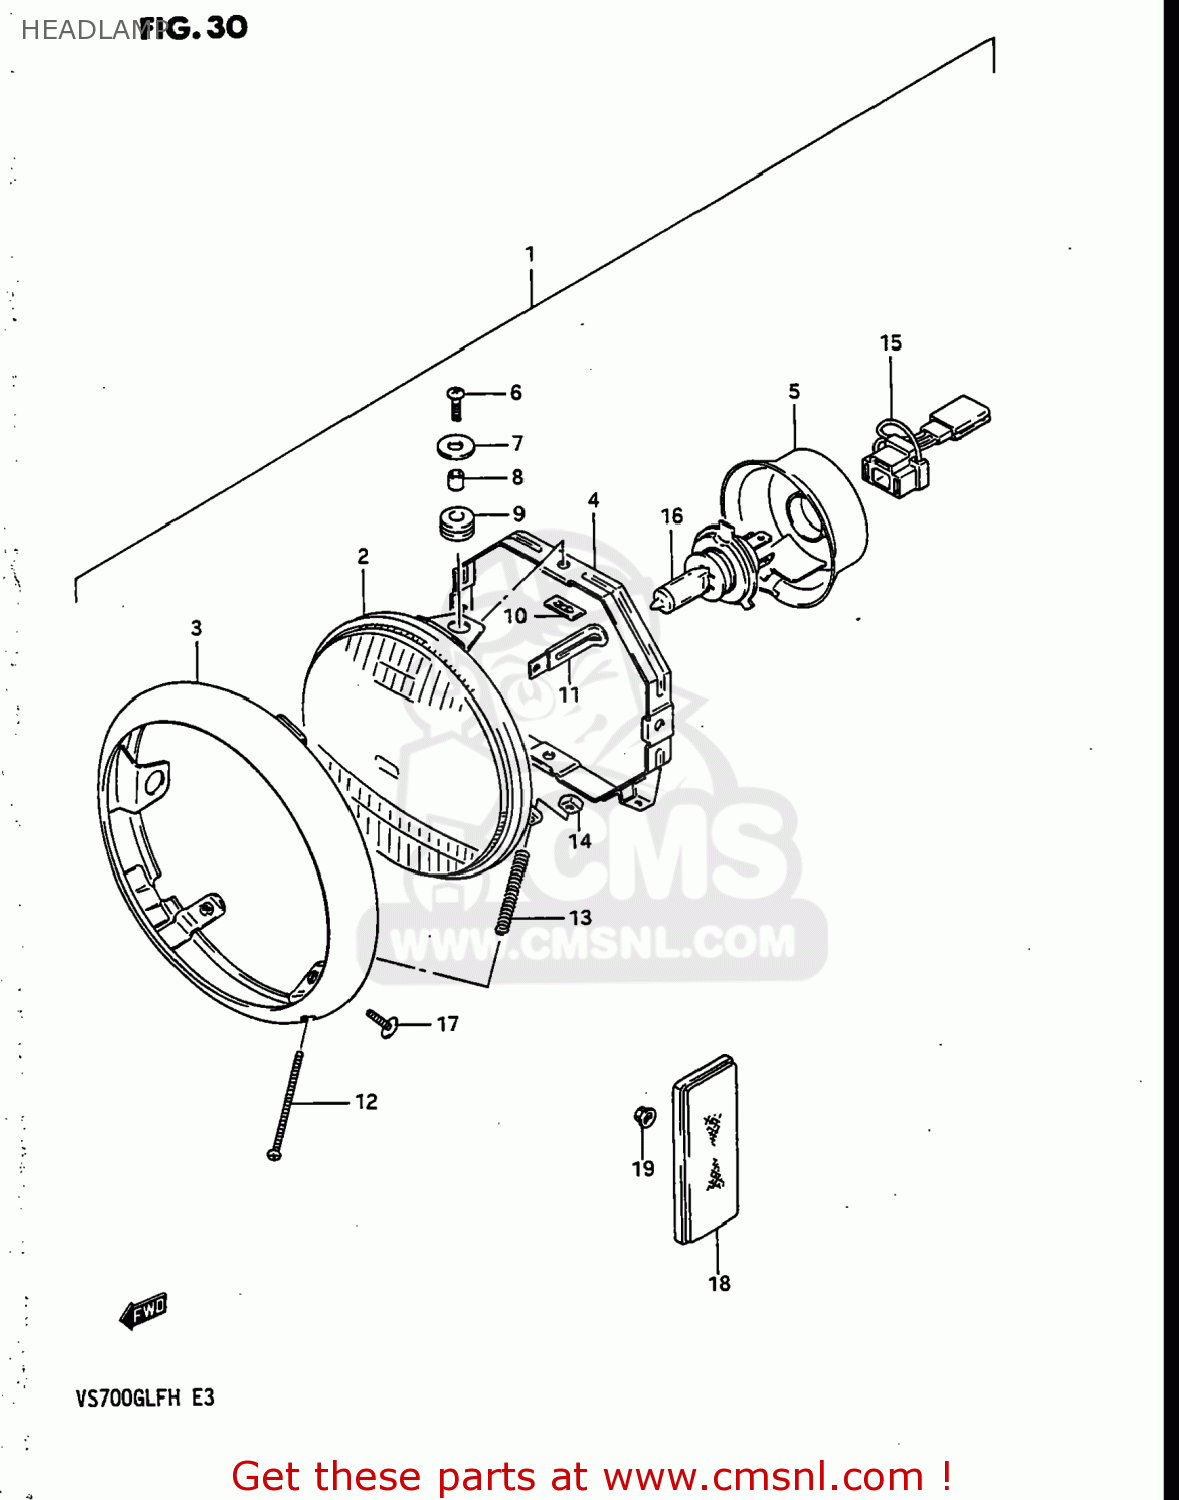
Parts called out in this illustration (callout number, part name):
1	HEADLAMP ASSY
2	UNIT,LAMP
3	RIM
4	RING,MOUNTING
5	COVER,SOCKET
6	SCREW(5X14)
7	WASHER
8	SPACER
9	CUSHION
10	NUT
11	CLAMP
12	SCREW,HEADLAMP ADJUST
13	SPRING,HEADLAMP ADJUST
14	NUT
15	SOCKET
16	BULB(12V60/55W,H4)
17	SCREW
18	REFLEX REFLECTOR,FR SIDE
19	NUT
